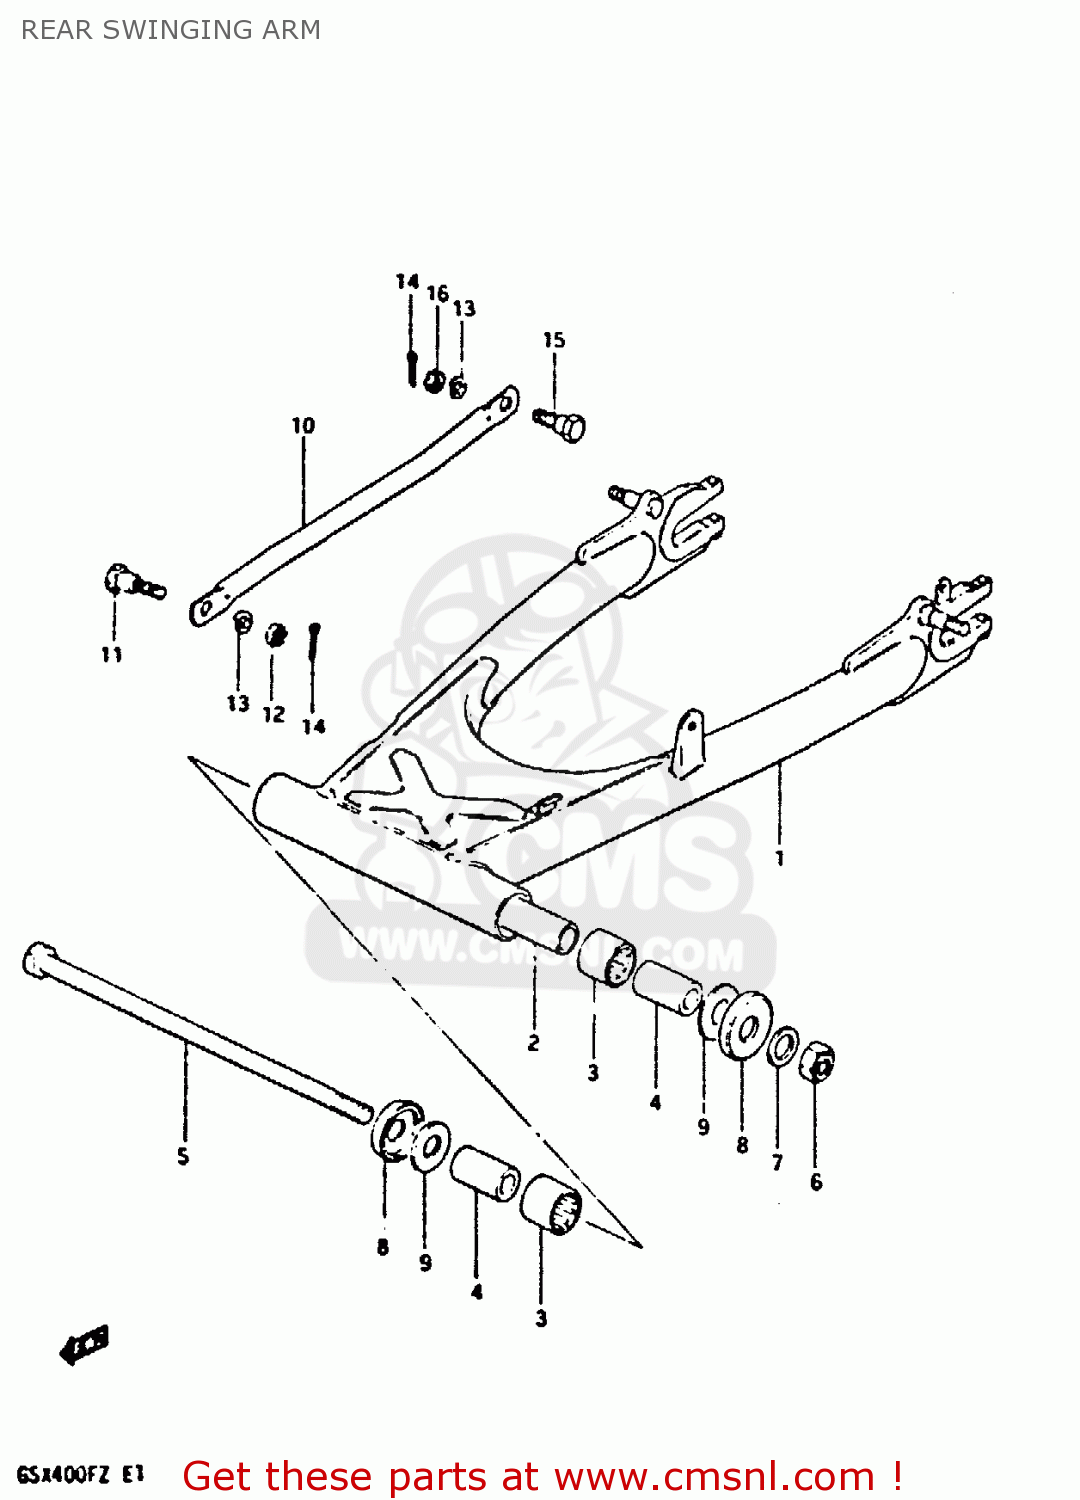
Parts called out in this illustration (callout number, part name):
1	REAR SWINGING ARM
2	SPACER,RR SWGARM PIVOT CTR
3	BEARING(22X29X30)
4	SPACER,RR SWGARM PIVOT
5	SHAFT,REAR SWING ARM
6	NUT 14MM
7	WASHER
8	CVR,RR SWGARM DUST SEAL(OD:40)
9	WASHER(14.2X34X1)
10	TORQUE LINK,REAR
11	BOLT(10X24.5)
12	NUT
13	LOCK WASHER
14	PIN 20X20
15	BOLT(10X31)
16	NUT
